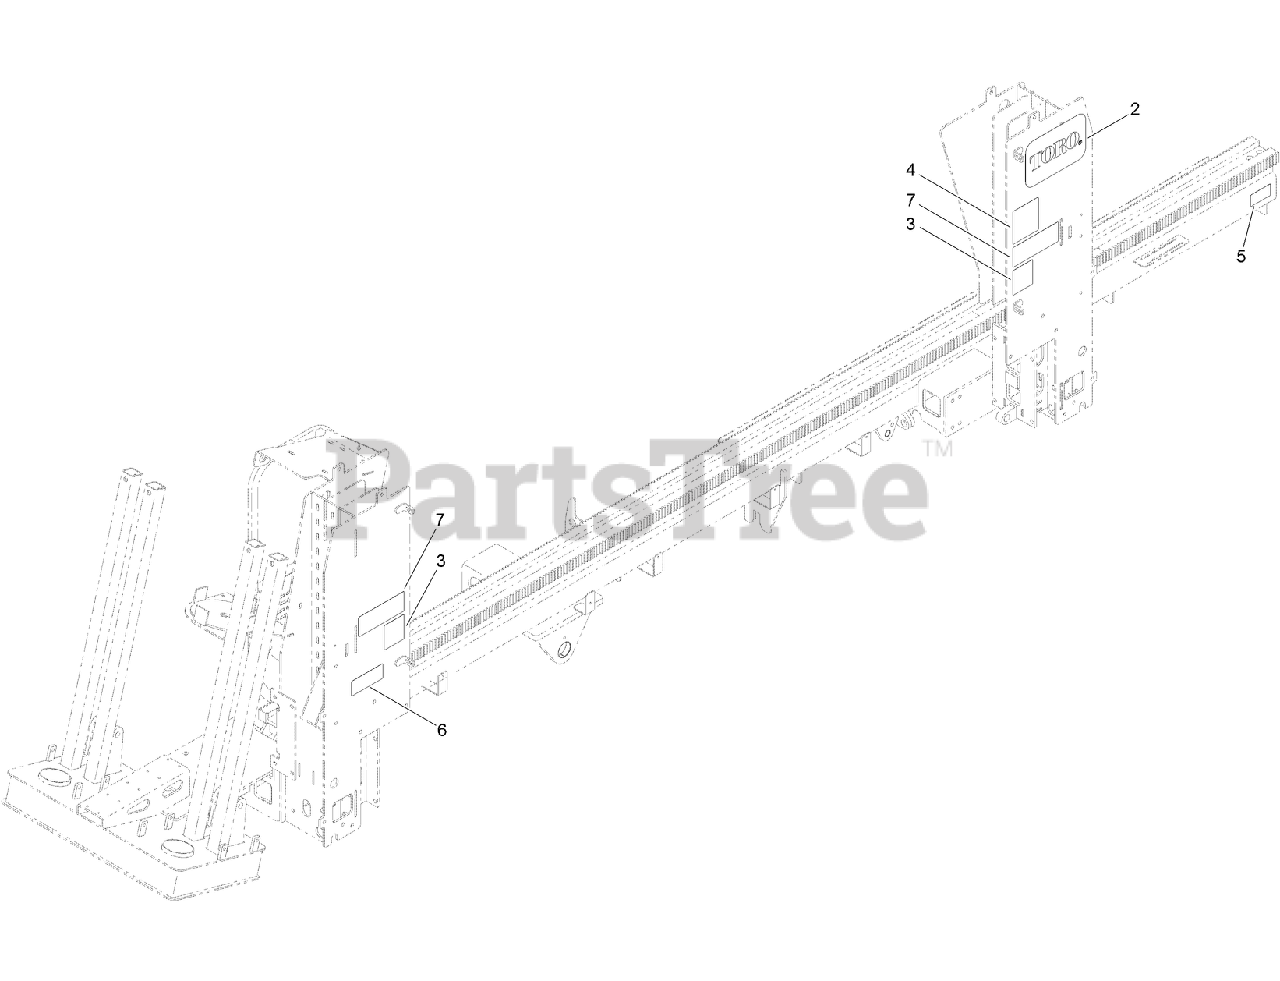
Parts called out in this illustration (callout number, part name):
3	DECAL-WARNING, CRUSHING
4	DECAL-SHOCK DANGER
5	DECAL-DANGER, CRUSHING
6	DECAL-WARNING, HYDRAULIC PRESSURE
7	DECAL-DANGER, HAZARDOUS AREA
